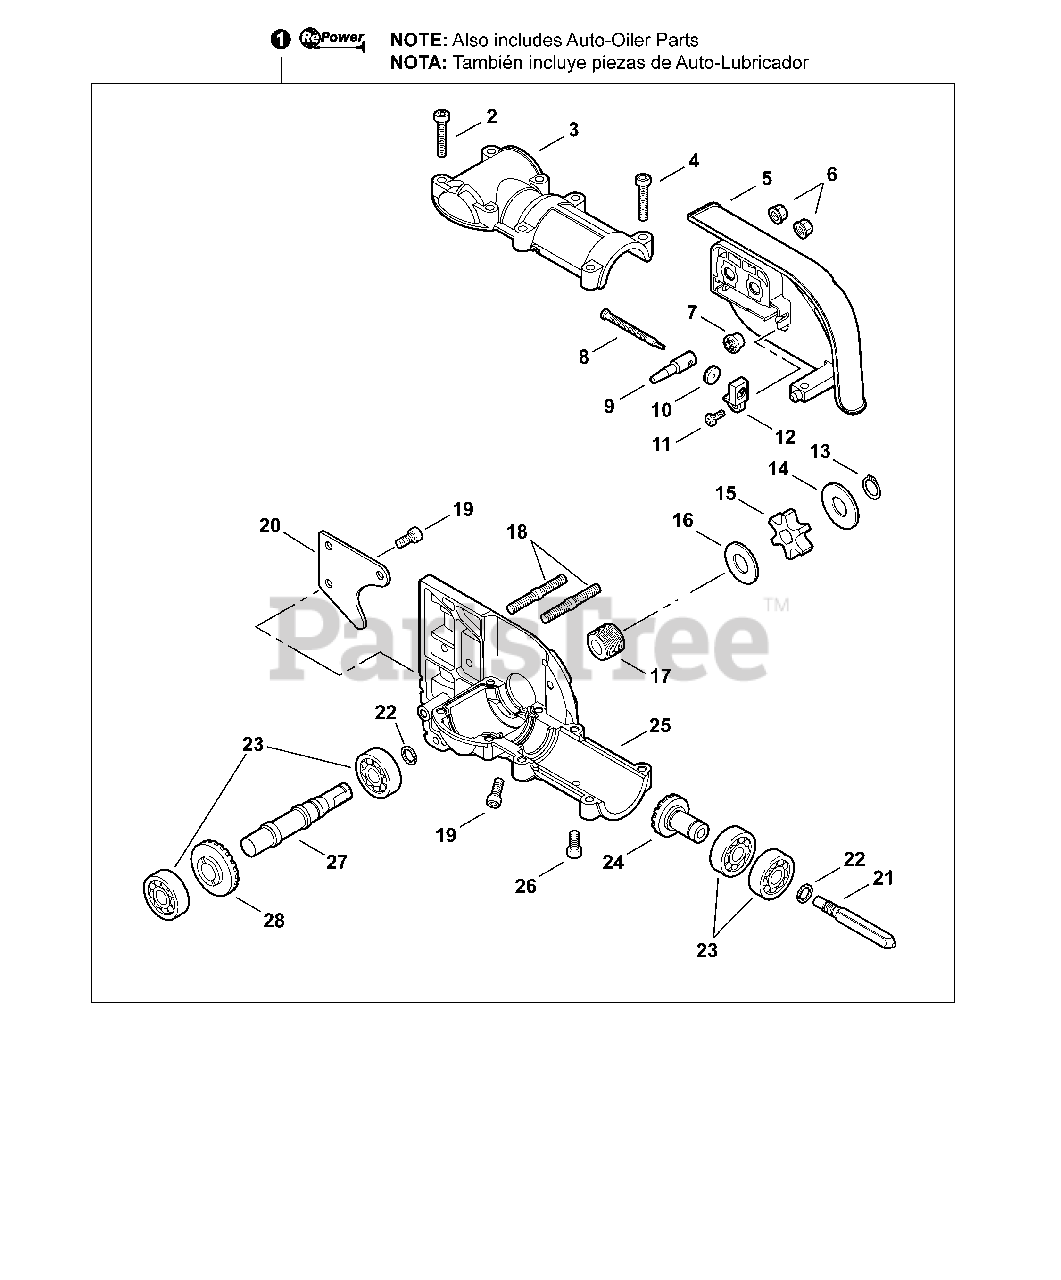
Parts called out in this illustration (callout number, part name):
1	CUTTING HEAD ASY
2	SCREW - 5×25
3	CASE, GEAR - UPPER
4	SCREW - 5×25
5	GUARD, SPROCKET
6	NUT - 6 -- FLANGE
7	GEAR - 14 TOOTH
8	SCREW, TENSIONER
9	TENSIONER, CHAIN
10	GEAR - 14 TOOTH
11	SCREW - 4×8
12	BRACKET, TENSIONER
13	RING, RETAINING
14	WASHER - 10
15	SPROCKET, DRIVE
17	GEAR, WORM
18	STUD, GUIDE BAR
19	SCREW - 5×10
21	CONNECTOR, SHAFT
22	RING, RETAINING - 12
23	BEARING, BALL - 6001
24	GEAR, BEVEL - 15 TOOTH
25	CASE, GEAR - LOWER
26	SCREW - 5×10
27	GEAR, SHAFT
28	GEAR, BEVEL - 23 TOOTH
